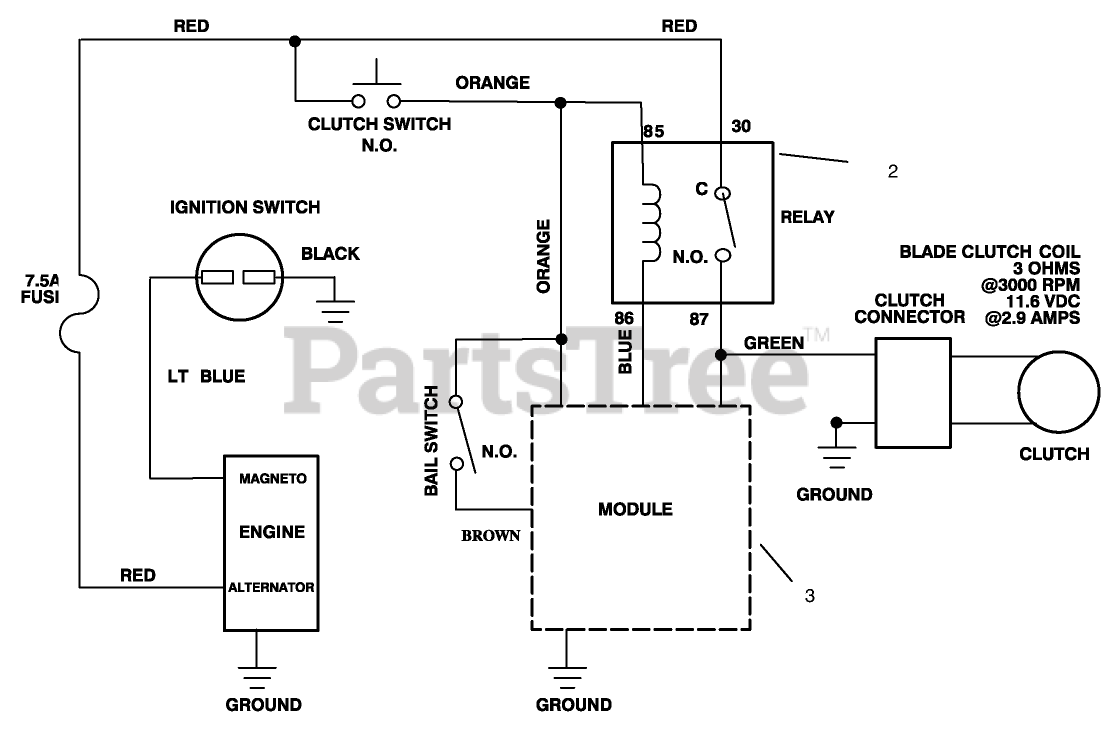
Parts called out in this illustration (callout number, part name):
1	HARNESS - WIRE
2	RELAY
3	MODULE
